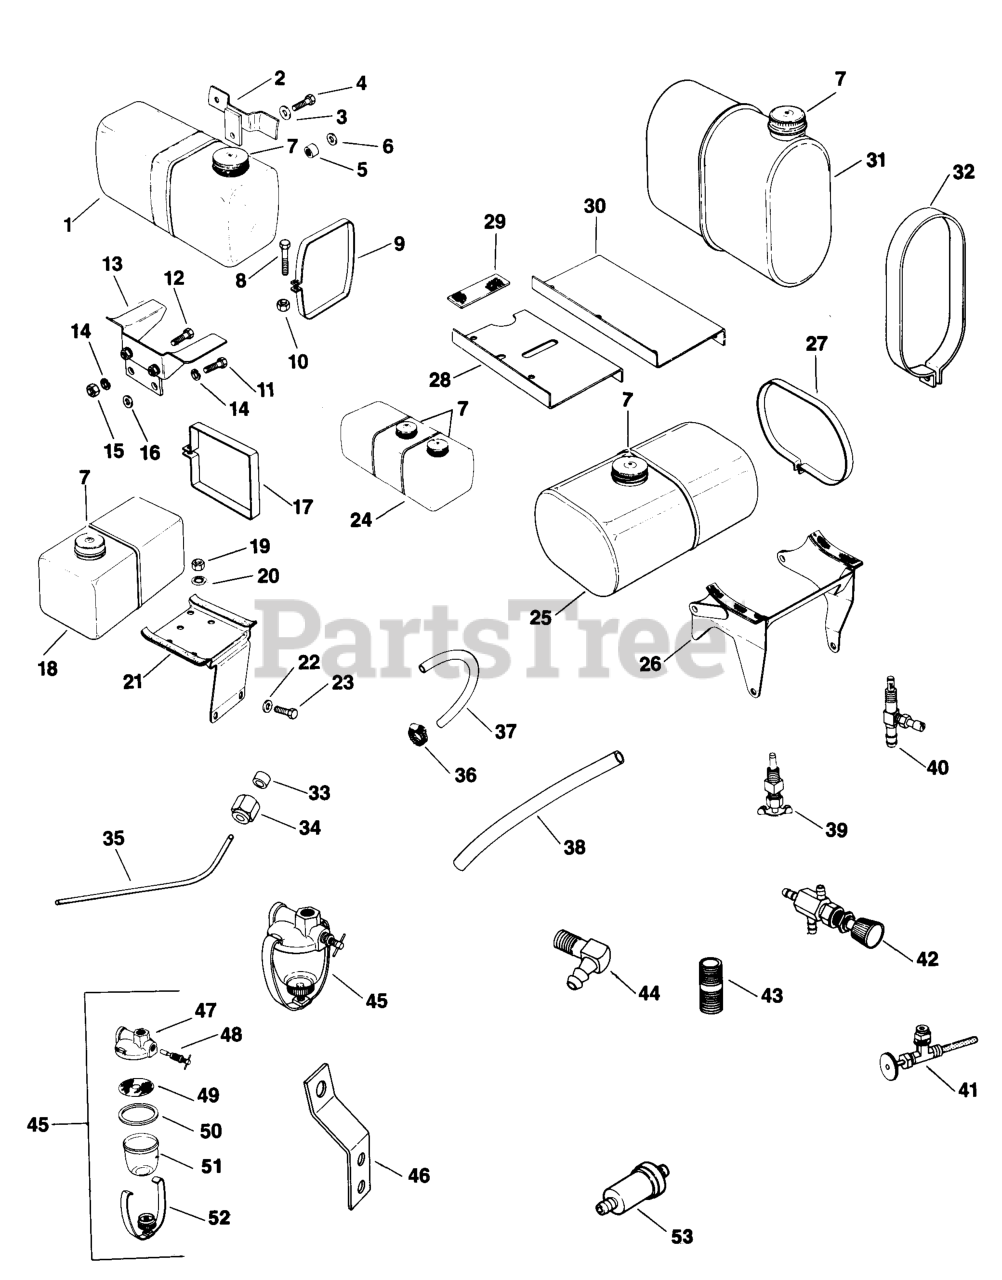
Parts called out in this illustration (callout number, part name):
1	TANK - DISCONTINUED
9	STRAP
10	NUT USE 25 100 13-S
13	BRACKET - (#DSC)
37	LINE - DISCONTINUED
38	SLEEVE - DISCONTINUED
39	VALVE
